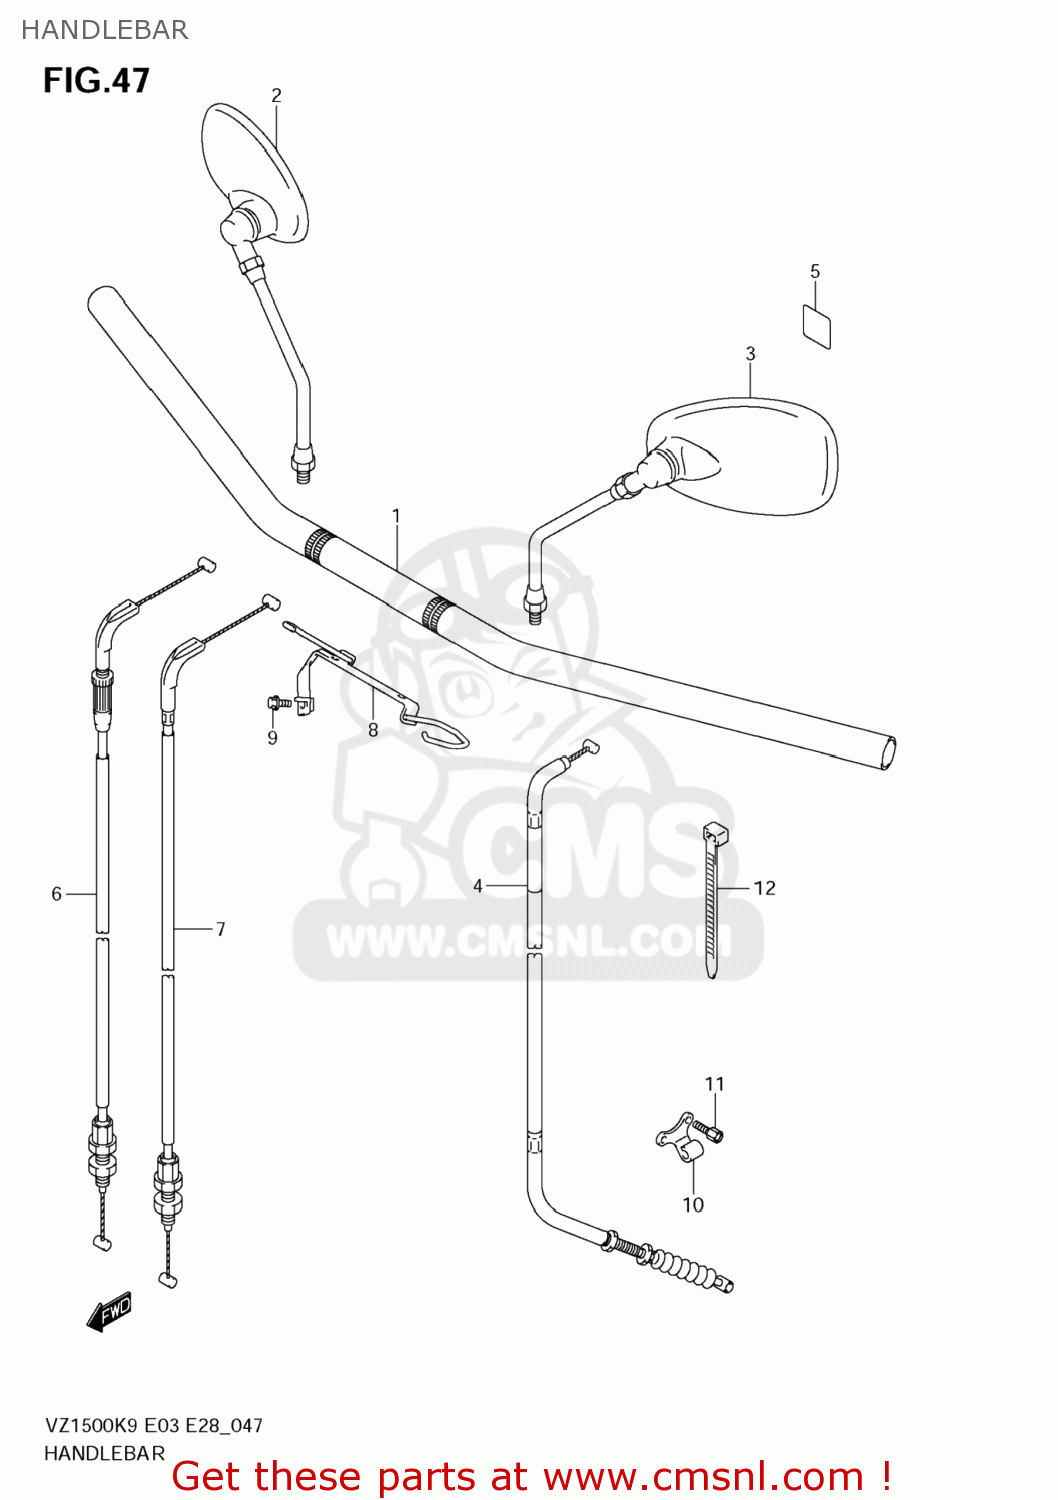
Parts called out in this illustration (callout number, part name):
1	HANDLEBAR
2	MIRROR ASSY,RR VIEW,R
3	MIRROR ASSY,RR VIEW,L
4	CABLE ASSY,CLUTCH
5	PROTECTOR
6	CABLE ASSY,THROTTLE NO.1
7	CABLE ASSY,THROTTLE NO.2
8	GUIDE,CABLE
9	BOLT
10	STOPPER,CLUTCH CABLE
11	BOLT
12	CLAMP(L:95)
